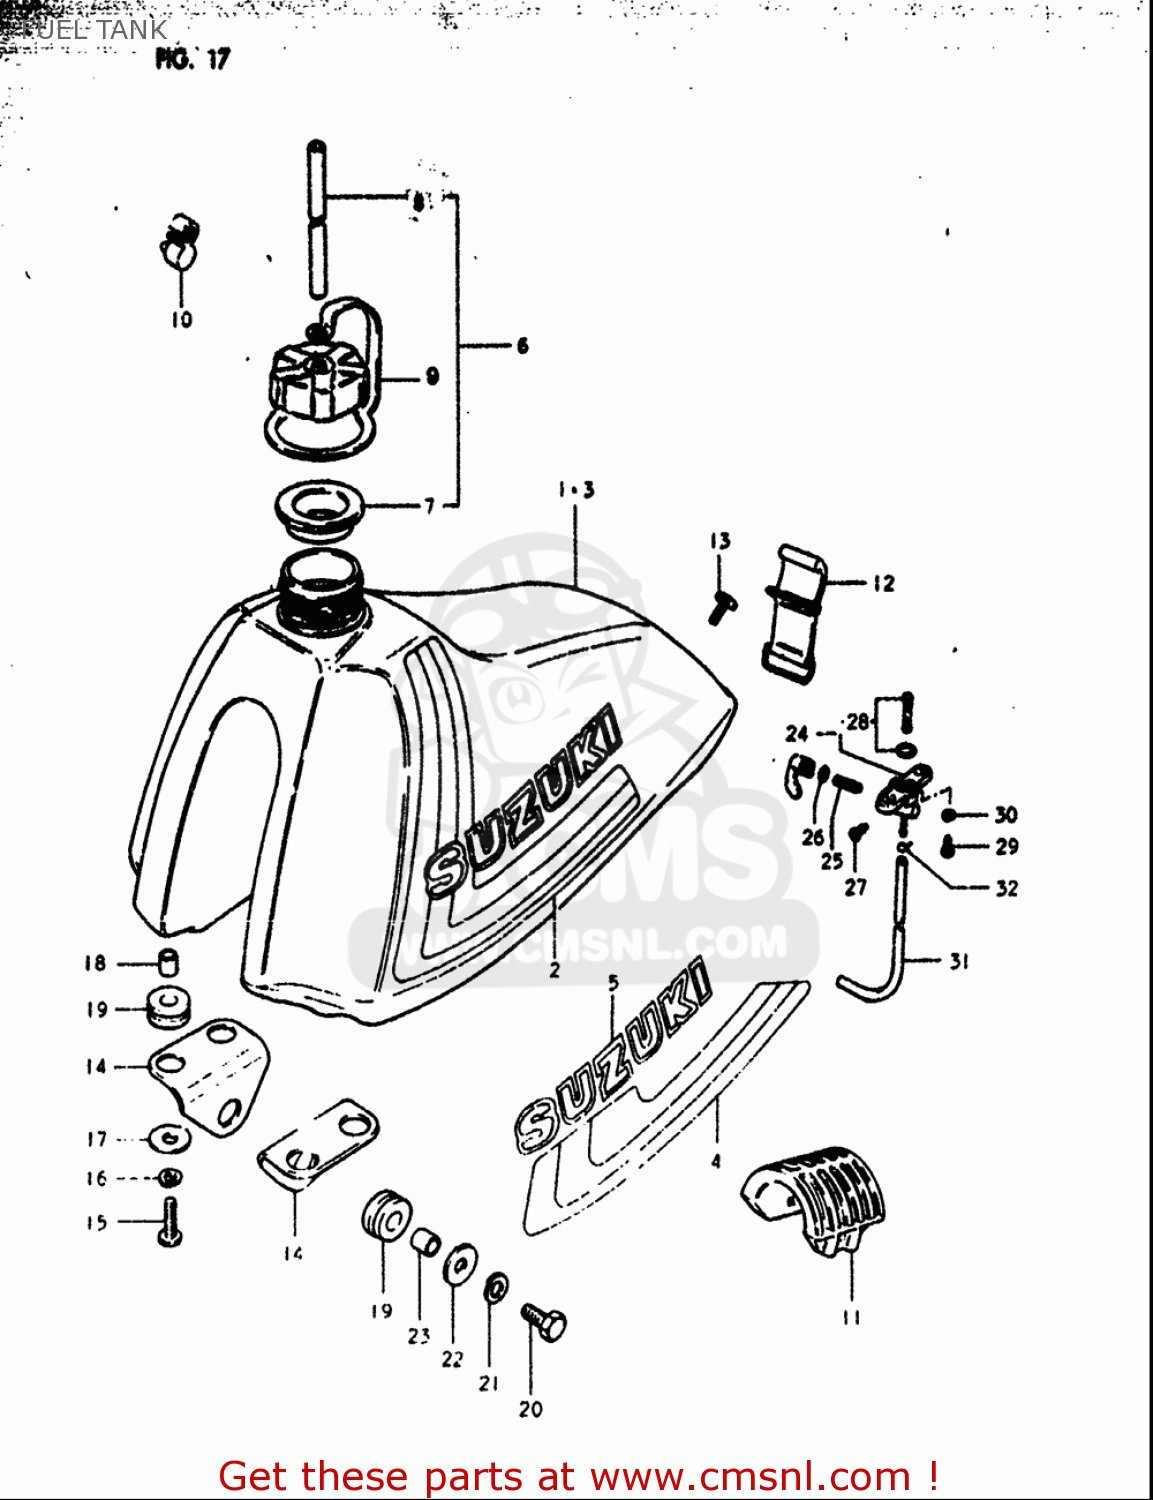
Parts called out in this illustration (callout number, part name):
5	EMBLEM
6	CAP SET,FUEL TANK
7	GASKET (NAS)
8	HOSE(5X8.2X600)
10	CLAMP,FUEL TANK BREATHER HOSE
12	BAND
13	SCREW(6X18)
15	SCREW
16	WASHER,LOCK
17	WASHER(6.5X24X1.6)
18	SPACER(6.8X12X11)
19	CUSHION
20	BOLT
21	WASHER,LOCK
22	WASHER(8.5X24X1.6)
23	SPACER(8.5X12X11)
24	COCK ASSY,FUEL
25	SPRING
26	O RING,LEVER
27	SCREW
28	FILTER SET FUEL
29	SCREW
30	WASHER,LOCK
31	HOSE(5X8.2X600)
32	CLIP
